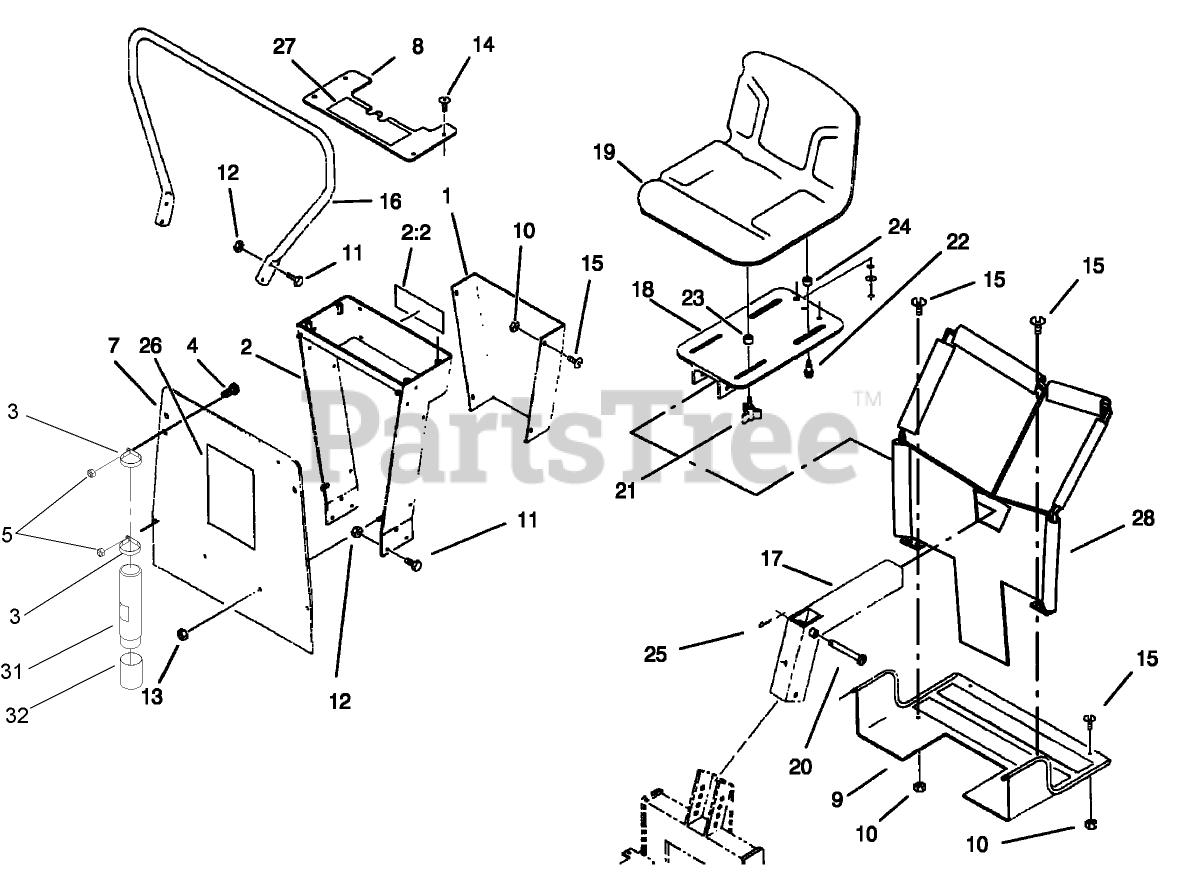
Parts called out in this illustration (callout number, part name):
1	GUARD-HOSE
2	VALVE MOUNT ASM
2:2	DECAL-WARNING
3	CLAMP-R
5	NUT-LOCK, NI
7	PANEL-FRONT
8	COVER-VALVE
9	FOOT PLATE ASM
10	NUT-LOCK
11	SCREW-HH
12	NUT-LOCK, NI
13	NUT-LOCK, NI
14	SCREW
16	HANDLE-GUARD
17	SEAT MOUNT ASM
18	SEAT PLATE ASM
19	SEAT
20	PIN-CLEVIS
22	BOLT-SHOULDER
23	SPACER-NYLON
24	SPACER-NYLON
25	PIN-COTTER
26	DECAL
27	DECAL-PANEL, CONTROL
28	BACKHOE SHIELD KIT
31	TUBE-MANUAL
32	CAP-HOUSING
